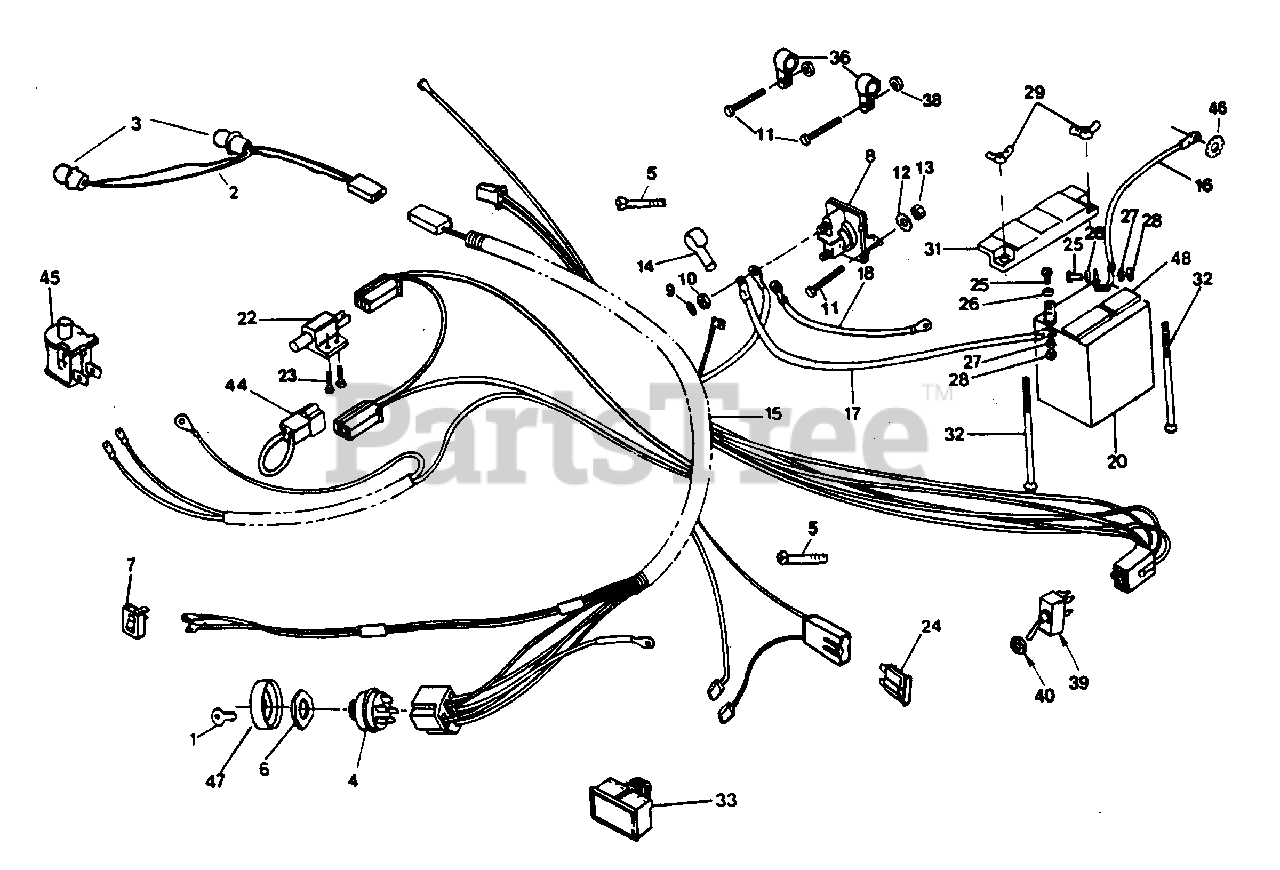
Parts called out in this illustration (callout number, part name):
1	Set Key (AYP part number)
2	Light Socket Harness (AYP part number)
3	Light Bulb (AYP part number)
4	Ignition Switch (AYP part number)
5	Cable Tie (AYP part number)
6	Hex Nut (AYP part number)
7	Light Switch (AYP part number)
8	Solenoid (AYP part number)
9	Lock Washer (AYP part number)
10	Jam Nut 1/4-20 (AYP part number)
11	Hex Bolt 1/4-20 x 1/2 Gr. 5 (AYP part number)
12	Lock Washer, Ext. Tooth (AYP part number)
13	Keps Nut (AYP part number)
14	Terminal Cover (AYP part number)
15	Ignition Harness
16	Battery Cable (AYP part number)
17	Battery Cable (AYP part number)
18	Ground Cable (AYP part number)
20	Battery Pack (AYP part number)
22	Interlock Switch (AYP part number)
23	Tap Washer Hex Screw (AYP part number)
24	30 Amp Fuse (AYP part number)
25	Hex Bolt 1/4-20 x 3/4 (AYP part number)
26	Washer 9/32 x 5/8 x 16 Ga. (AYP part number)
27	Lock Washer 1/4 (AYP part number)
28	Hex Nut 1/4-20 (AYP part number)
29	Wing Nut 1/4-20 (AYP part number)
31	Terminal Guard (AYP part number)
32	Sq. Neck, Round Hd. Bolt (AYP part number)
33	Ammeter (AYP part number)
36	Insulation Clip (AYP part number)
38	Crownlock Nut (AYP part number)
39	P.T.O. Switch (AYP part number)
40	Hex Nut (AYP part number)
44	Wire Loop (AYP part number)
45	Plunger Switch (AYP part number)
46	Ext. Tooth Lock Washer (AYP part number)
47	Ignition Bezel (AYP part number)
48	Battery Caps (AYP part number)
